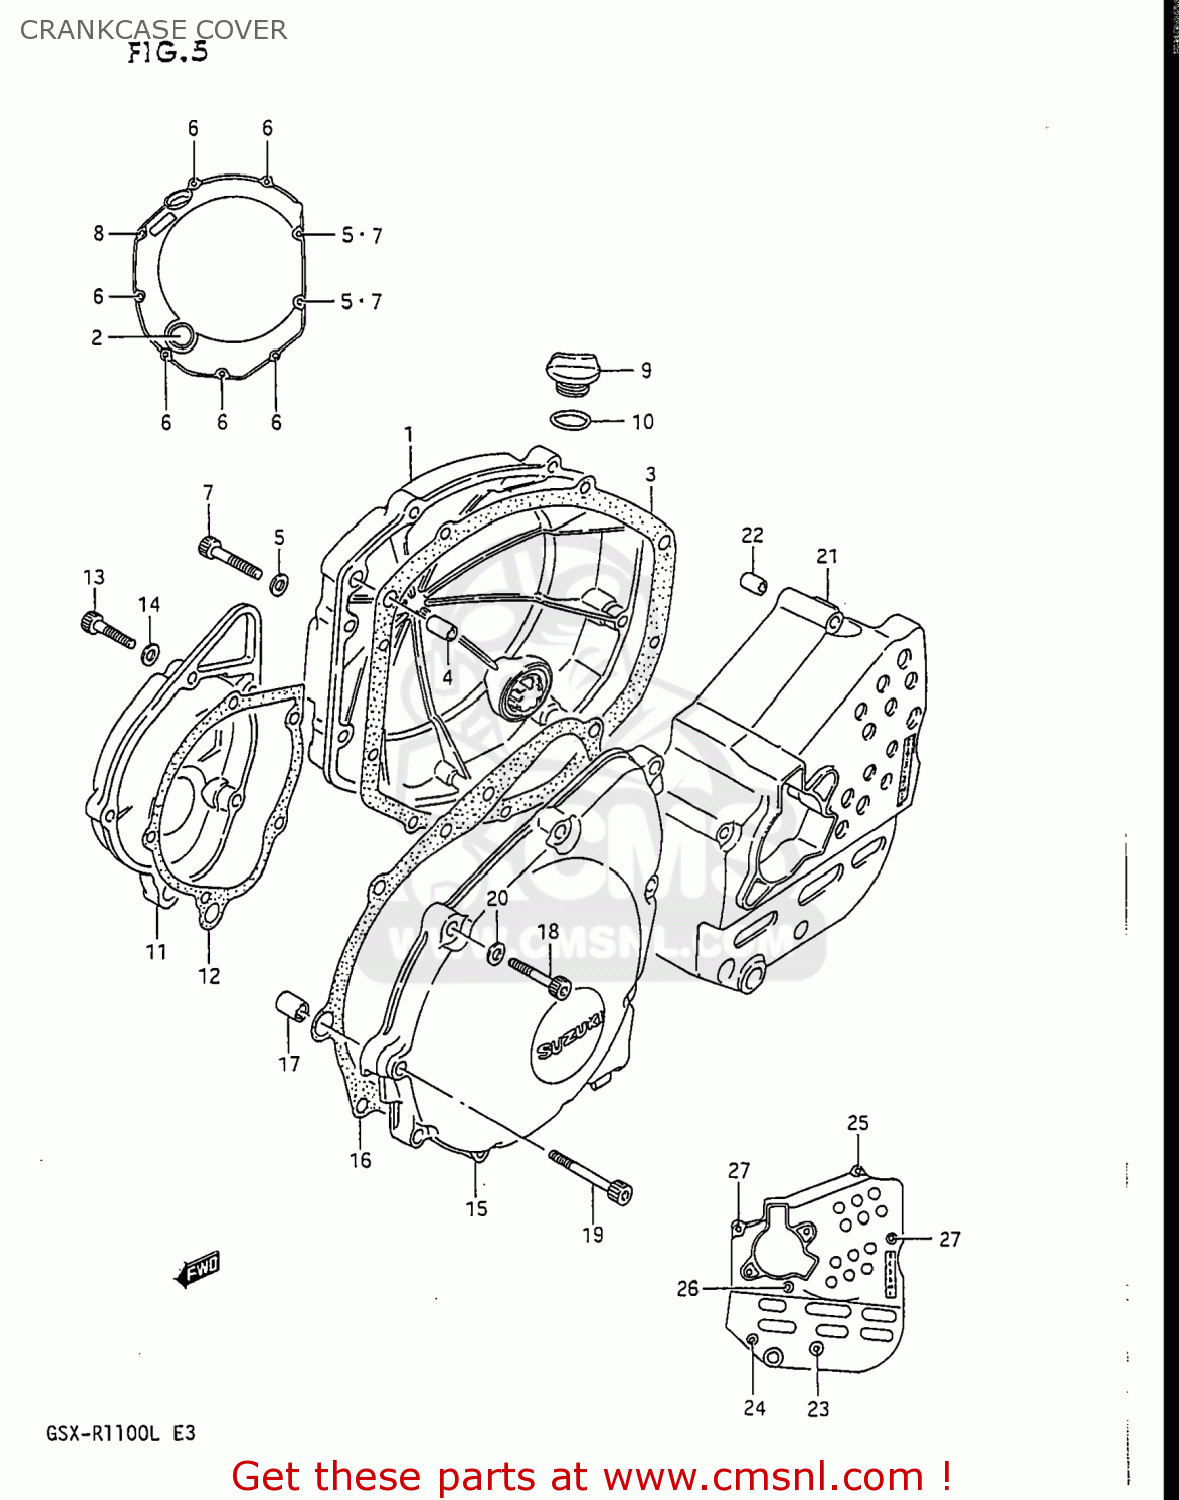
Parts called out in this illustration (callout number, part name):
1	COVER,CLUTCH
2	LENS,OIL LEVEL CHECK
3	GASKET,CLUTCH COVER (MCA)
4	PIN
5	GASKET(5.8X11X1.2) (NAS)
6	BOLT
7	BOLT
8	BOLT
9	PLUG
10	O RING(D:3.1,ID:16.8)
11	COVER,SIGNAL GENERATOR
12	GASKET,SIGNAL GENERATOR COVER (NAS)
13	BOLT
14	GASKET(5.8X11X1.2) (NAS)
15	COVER,STARTER GEAR
16	GASKET,STARTER GEAR COVER (NAS)
17	PIN (11X20)(SUS)
18	BOLT
19	BOLT
20	GASKET(5.8X11X1.2) (NAS)
21	COVER,SPROCKET
22	PIN
23	BOLT
24	BOLT
25	BOLT
26	BOLT
27	BOLT
